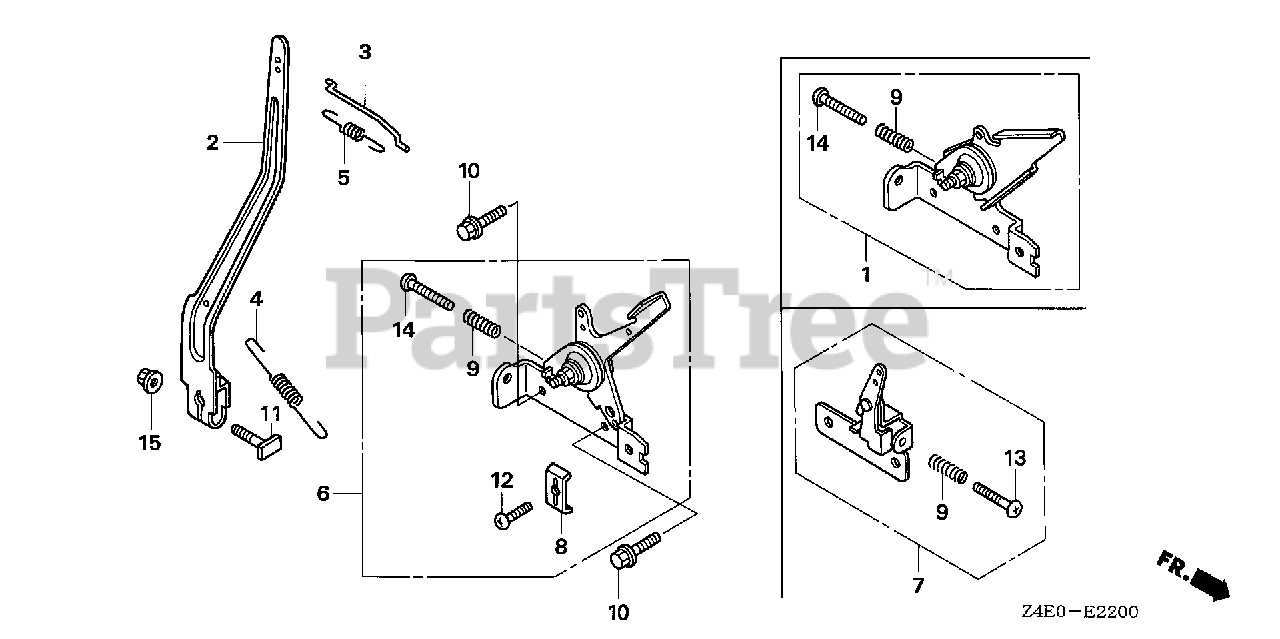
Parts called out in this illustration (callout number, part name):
2	ARM, GOVERNOR
3	ROD, GOVERNOR
4	SPRING, GOVERNOR
5	SPRING, THROTTLE RETURN
6	CONTROL ASSY. (STD)
8	HOLDER, CABLE
9	SPRING, CONTROL ADJUSTING
10	BOLT, FLANGE (6X14) (CT200)
11	BOLT, GOVERNOR ARM
12	SCREW, PAN (5X16)
14	SCREW, PAN (5X25)
15	NUT, FLANGE (6MM)
